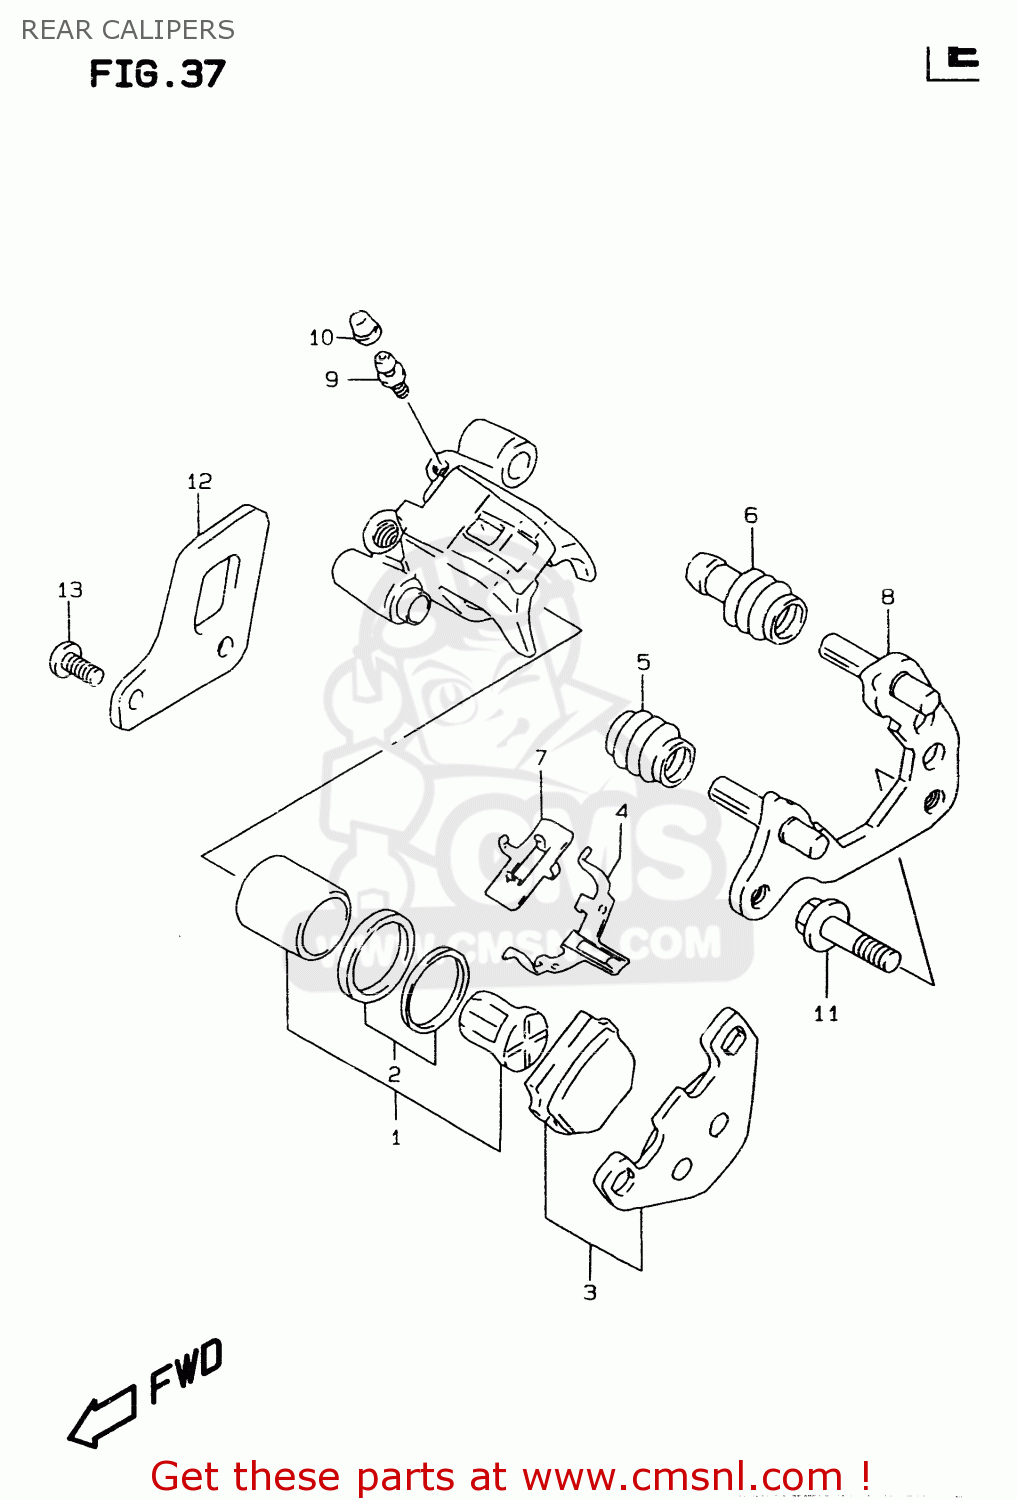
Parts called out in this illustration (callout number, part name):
1	PISTON SET
2	SEAL SET,PISTON
3	PAD SET (NAS)
4	SPRING,PAD
5	BOOT,AXLE
6	INSULATOR,AXLE
7	SHIM
8	CARRIER,CALIPER
9	BLEEDER
10	CAP,BLEEDER PLUG
11	BOLT(8X18)
12	GUARD,RR CALIPER
13	SCREW(6X12)
